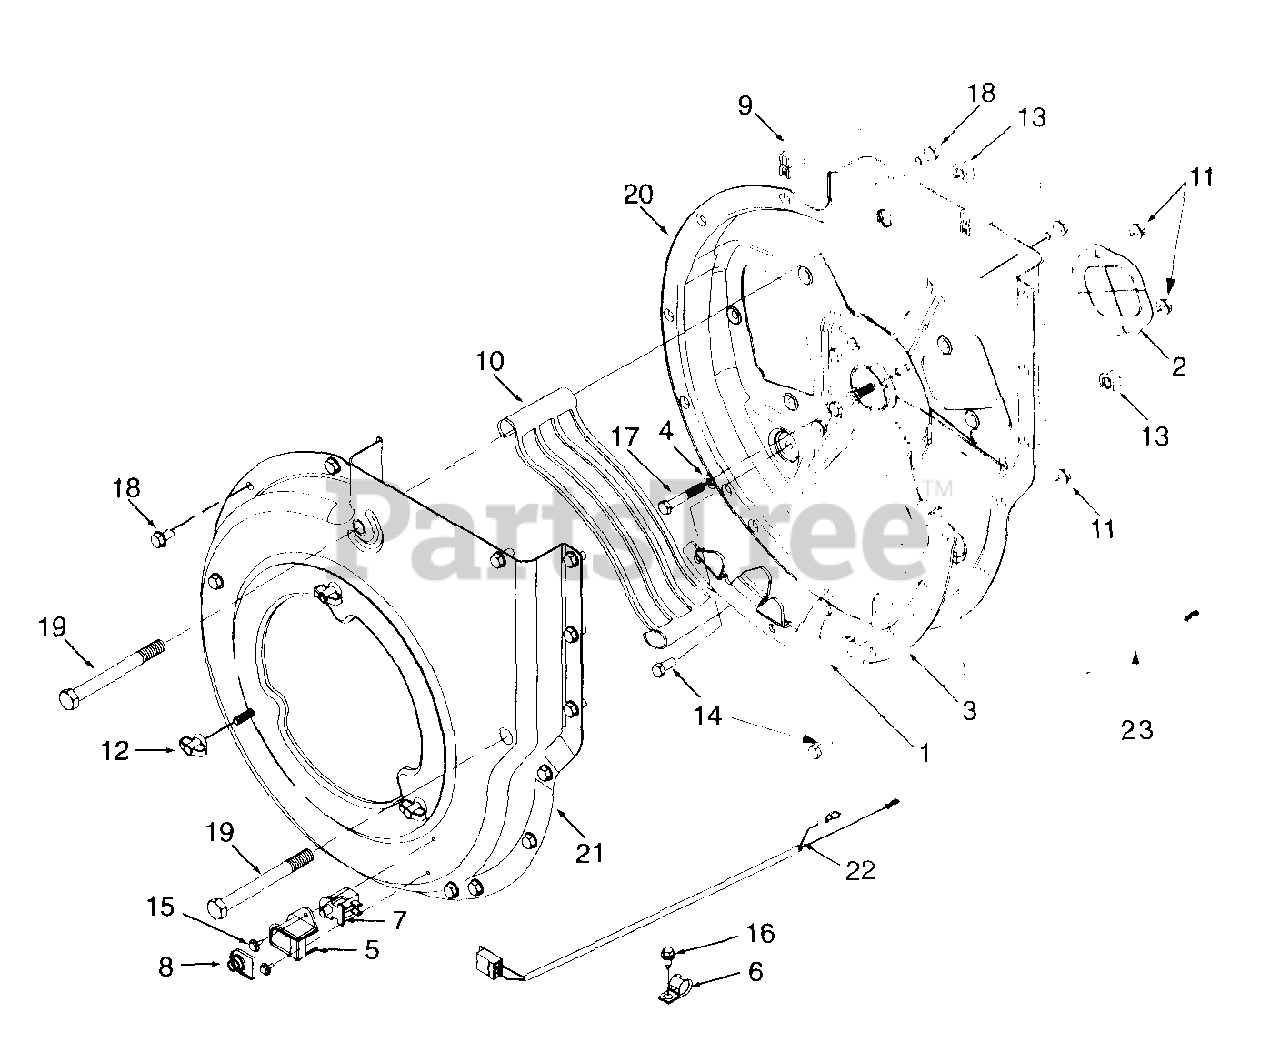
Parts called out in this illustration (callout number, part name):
4	Washer, Lock, 5/16
5	Cover, Safety Switch Mtg
7	Switch, Snap Mount
8	Cover, Switch
9	Rubber Seal
10	Screen, Discharge
11	Nut, Hex Flange Lock, 5/16-18
12	Knob, 5/16-18
13	Nut, Hex Center Lock, 1/2-13
14	Screw, Hex Cap, 5/16-18 x .75GR5
15	Screw, Wash Hd Tapp #10-16
16	Screw, Wash Hd Tapp 1/4-141
17	Screw, Hex Cap, 5/16-18 x 2 GR
18	Screw, Wash Hd Tapp 5/16-18
19	Screw, Hex Cap, 112-13 x 5.0
20	Housing Ass'y, Inner Flail
21	Housing Ass'y, Outer Flail
22	Harness, Wire
23	Adapter, Harness
